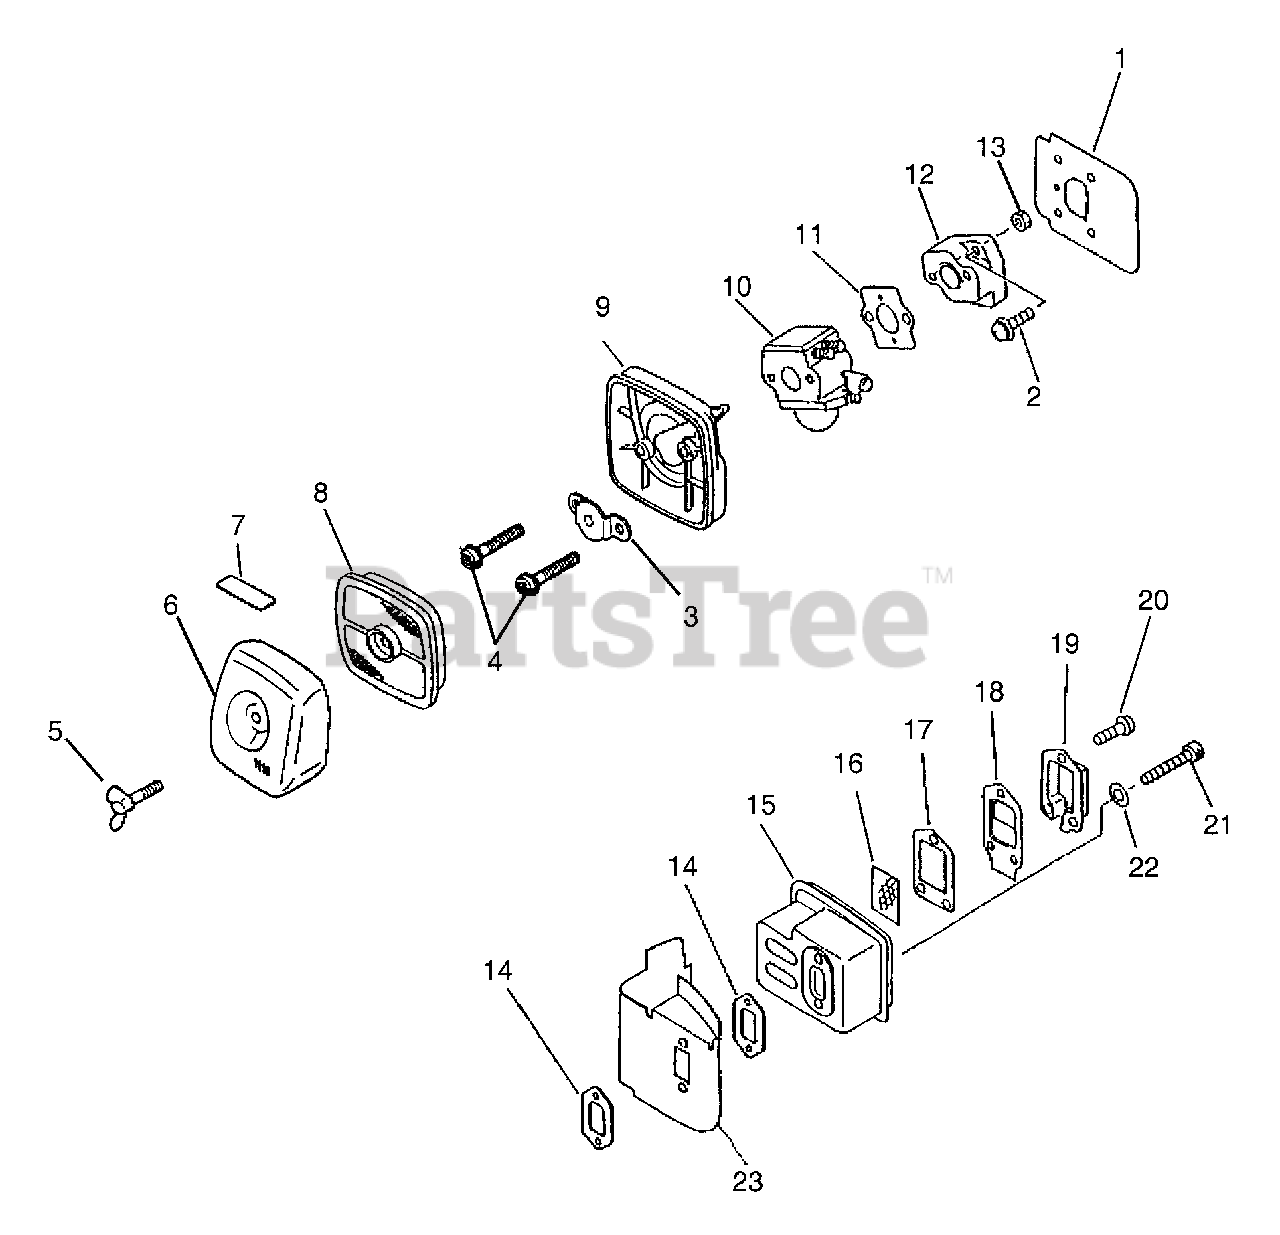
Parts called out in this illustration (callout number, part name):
1	HEAT SHIELD, INTAKE
2	SCREW 5×20
3	PLATE, PREVENT
4	SCREW 5×65
5	BOLT, WING 5×20
6	COVER, AIR FILTER - GRAY
7	LABEL, CHOKE
8	FILTER, AIR
8	FILTER, AIR - SINGLE LAYER
9	AIR FILTER CASE ASSY
10	CARBURETOR - C1U-K51
11	GASKET, INTAKE
12	INSULATOR, INTAKE
13	NUT M5
14	GASKET, EXHAUST
16	SCREEN, SPARK ARRESTER
17	GASKET, EXHAUST
18	GUIDE, EXHAUST
19	GUIDE, EXHAUST - INNER
20	SCREW 4×10
21	BOLT 5×55
22	WASHER, FLAT 5.5×10×0.8
23	COVER, EXHAUST
